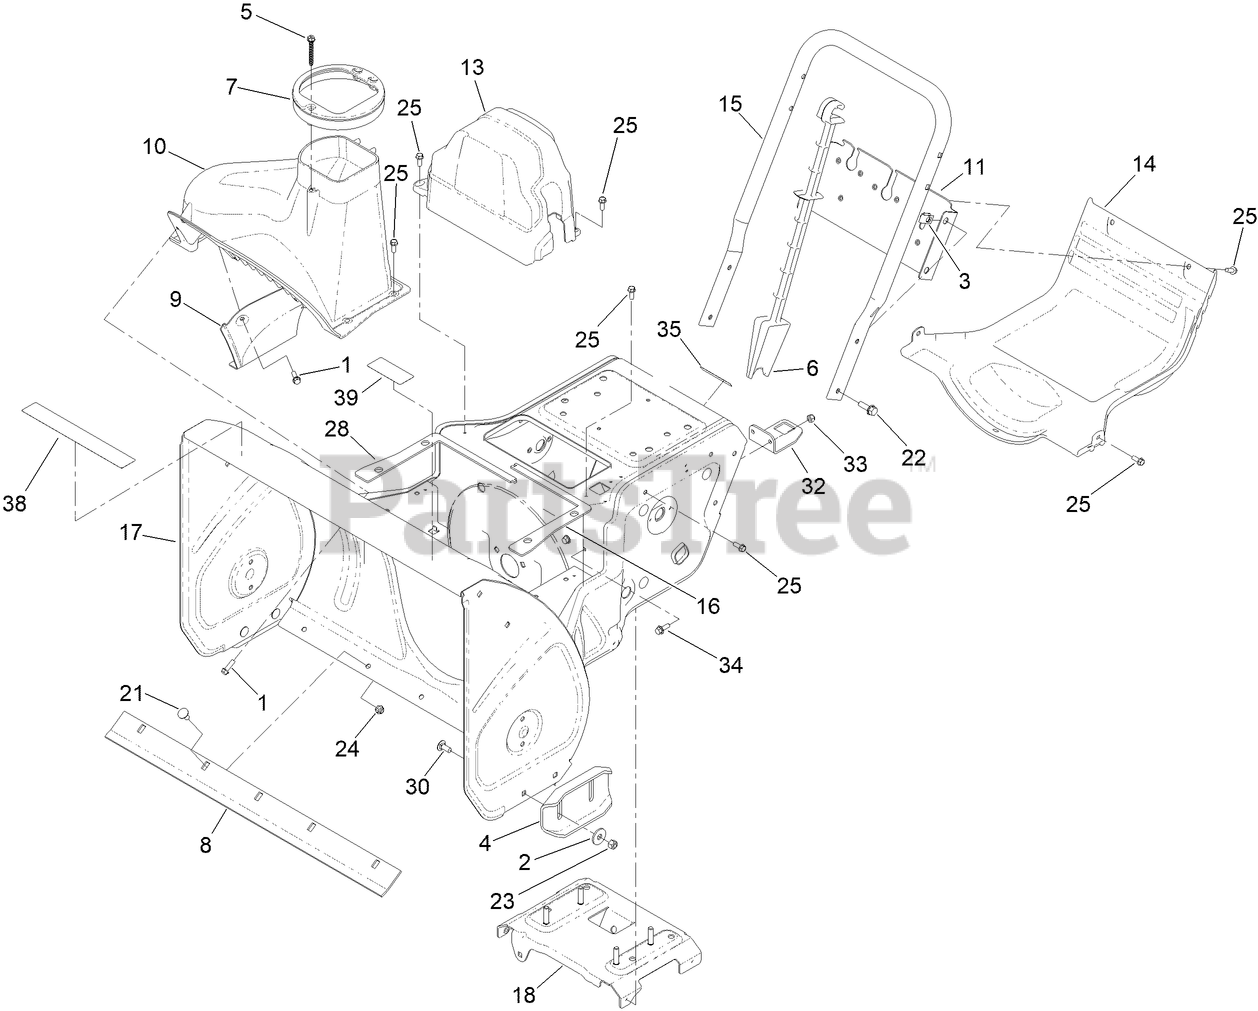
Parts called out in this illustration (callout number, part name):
1	SCREW-HWH
2	WASHER
3	NUT-U
5	SCREW-HWH, PLASTITE
6	STICK-CLEANOUT
7	GUIDE-CHUTE
8	SCRAPER-26 INCH
9	COVER-LINER
11	BRACE-FRAME
13	COVER-BELT
14	COVER-LOWER
15	HANDLE-LOWER, CTS
16	SEAL-HOUSING, LH
17	FRAME ASM
18	BRACE-FRAME
21	SCREW-CARR
22	SCREW-HHF
23	NUT-LOCK, NI
24	NUT-LOCK, NI
25	SCREW-HWH
28	SEAL-HOUSING, RH
30	SCREW-CARR
32	BRACKET-POST, CHUTE
33	SCREW-HHF
34	NUT-HEX
35	DECAL-WARNING
38	DECAL - HARDENED GEARS
39	DECAL - COMPACT 26
